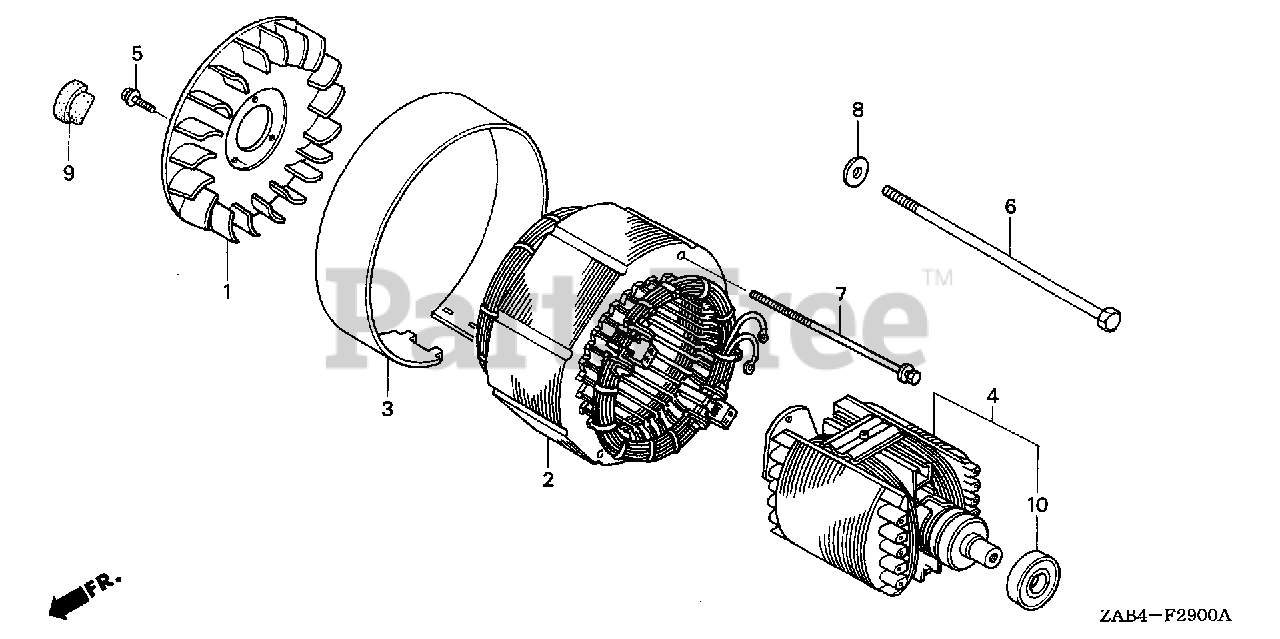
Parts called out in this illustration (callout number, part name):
1	FAN, GENERATOR COOLING
2	STATOR ASSY.
3	COVER, STATOR
4	ROTOR
5	SCREW, TAPPING (5X14)
6	BOLT, HEX. (10X265)
7	BOLT-WASHER (5X210)
8	WASHER (10.5MM)
9	GROMMET, CRANKCASE
10	BEARING ASSY. (6204)
